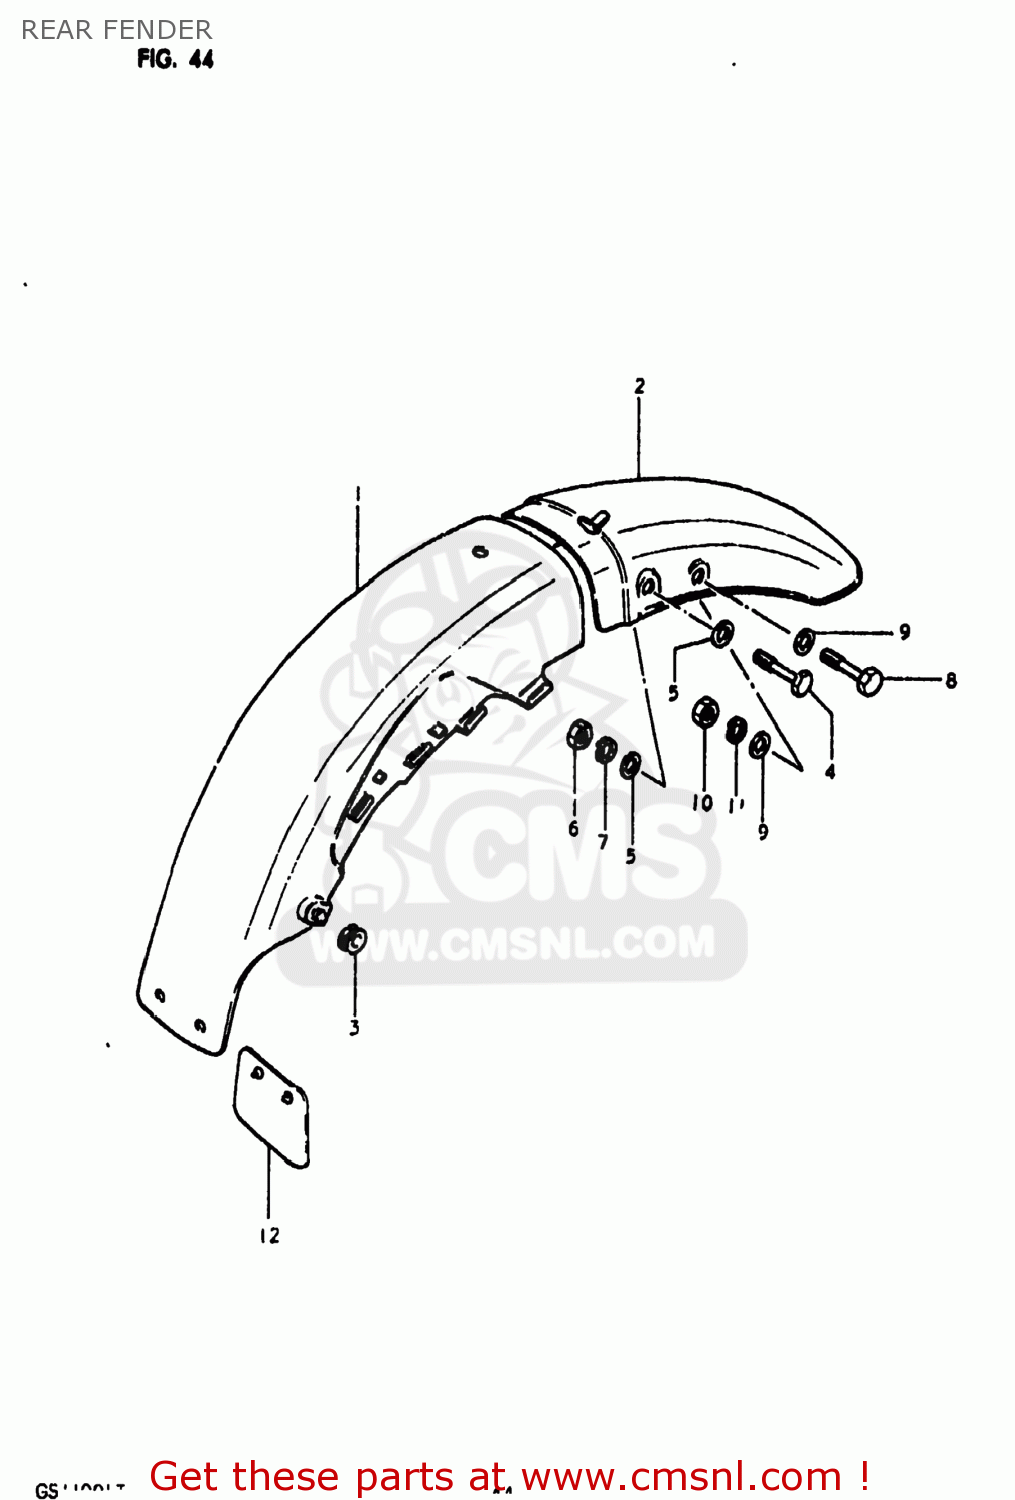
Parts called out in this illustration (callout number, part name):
1	FENDER,REAR
2	FENDER,REAR
3	CUSHION
4	BOLT
5	WASHER
6	NUT
7	LOCK WASHER
8	BOLT
9	WASHER
10	NUT 8MM
11	LOCK WASHER
12	GUIDE,RR FENDER MUD
